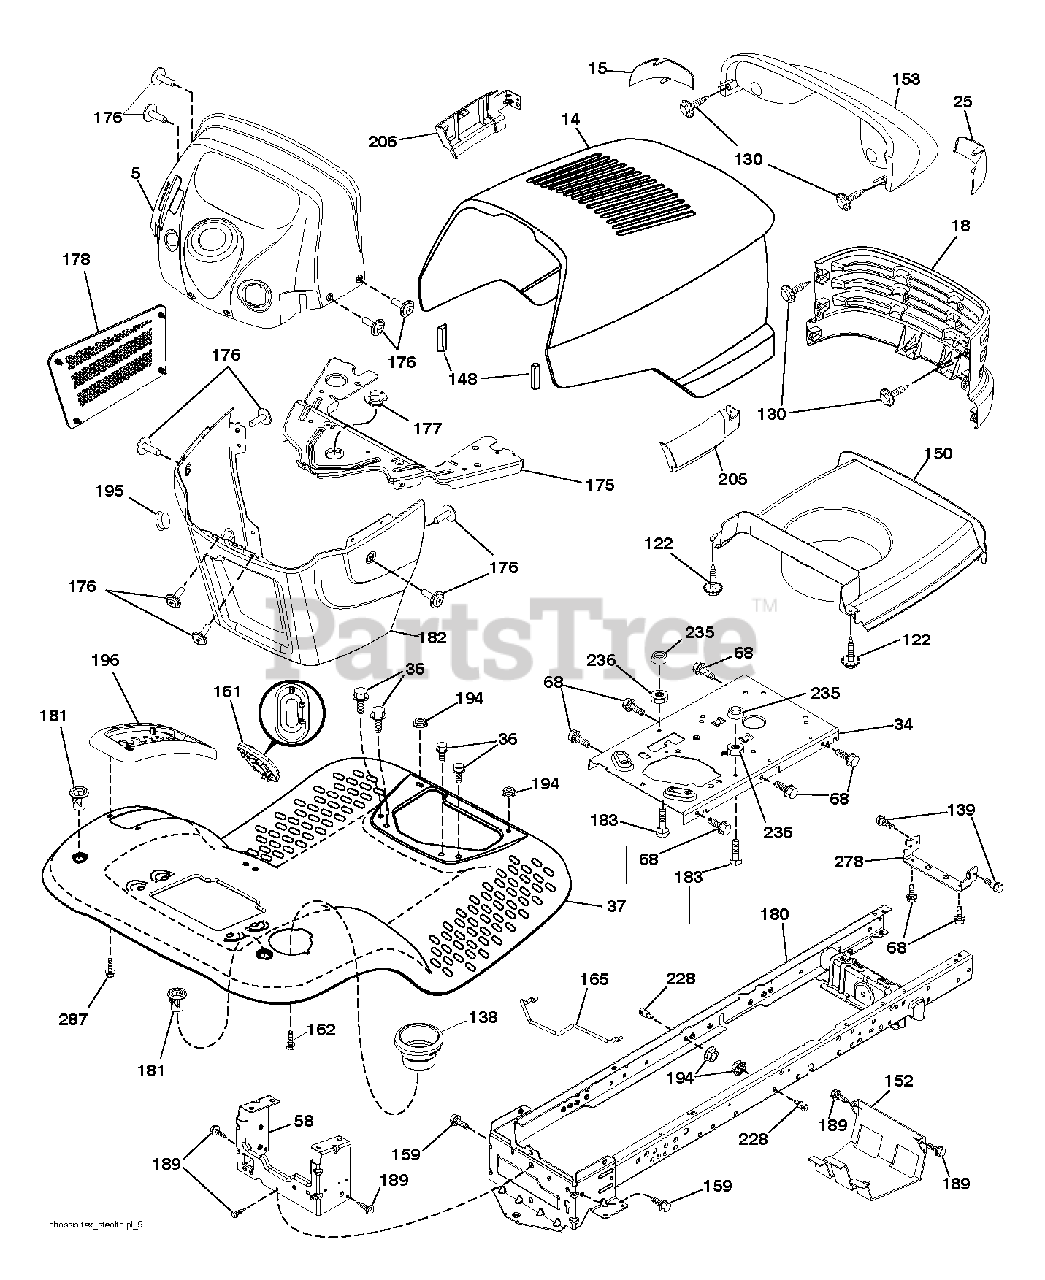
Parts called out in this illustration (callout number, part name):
5	DASH.UPR.STEALTH
15	LENS LH
25	LENS RH
34	PLATE.ENGINE.WELDED.CH
37	FENDER.TLT.W/CPH.W/FW.666
58	DRAWBAR UPPER
68	SCREW LT
130	SCREW.#10 X 0.750.BOS THREAD
138	CUPHOLDER
148	EXTRUSION BUMPER
150	DUCT HEAT HOOD
152	SHIELD BROWNING
159	SCREW, 3/8-16X3/4
161	WINDOW.FUEL.LT.TEX.428
162	SCREW,HEX
165	SUPPORT.TANK.REAR.W/TE
175	CROSSMEMBER.
176	SCREW.#10-24X5/8.RN.QU
177	BUSHING.STEERING.YT/GT
178	CARGO.ASM.NET.DASH.LOWER
180	CHASS.WLDMNT.TL.12GA/2P.48/54
181	FEND/FTRST.PCH.CPH.NFW
182	DASH.LOWER.
183	BOLT.5/16-18X1-1/4 FULL THD
189	SCREW
194	NUT LOCK HEX FLANGE 5/16-18
195	PLUG.HOLE.DASH.LOWER.1
196	CONSOLE ASM. DECK LIFT
205	SKIRT.GRILLE.STEALTH.RH
206	SKIRT.GRILLE.STEALTH.LH
228	STUD.FASTNER.W/D.ANTI-
235	SPACER FENDER
236	JAM LOCK NUT
278	BRKT.HOOD/MUFF.STEALTH
